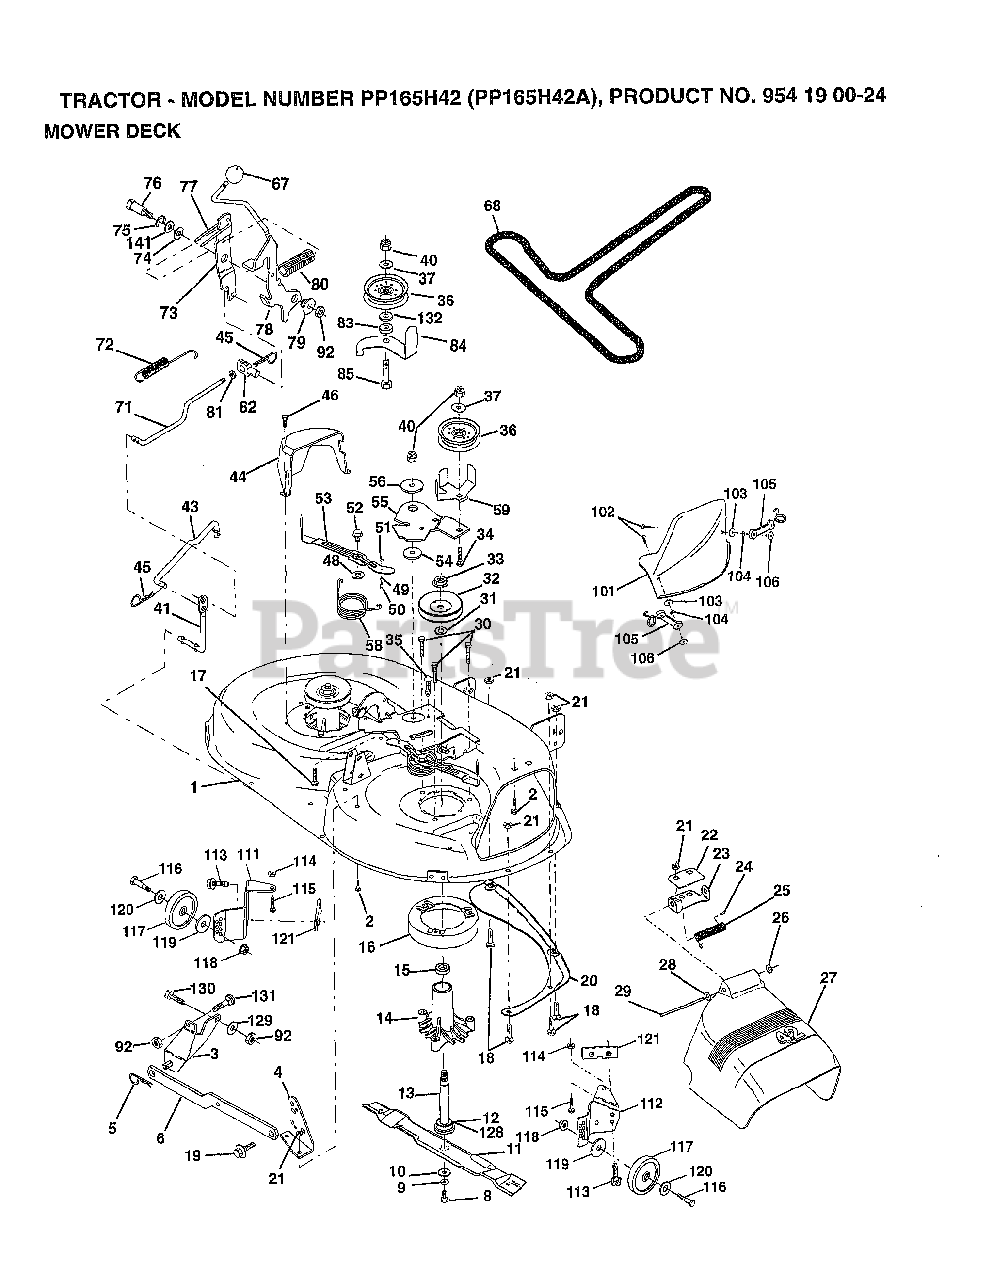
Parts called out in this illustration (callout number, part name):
1	DECK.WELD.42.
2	BOLT
3	BRKT ASM SWAY BAR
4	BRKT DECK SW BAR
8	BLADE BOLT
10	WASHER.HARD.BLADE
11	"BLADE.42"" MULCHER"
12	BEARING.BALL
14	HSG ASM MANDREL
15	BEARING
16	STRIPPER RND MWR
17	BOLT RDHD 3/8-16
18	BOLT
19	BOLT SHD 5/16-18
20	BAFFLE VORTEX 42
22	STIFFENER BRKT
23	DEFLECTOR BRKT
25	SPRING TORSION
27	DEFLECTOR.SHIELD
28	WASHER
29	HINGE ROD
30	"SCREW-THD ROLL,WA"
31	WASHER
32	PULLEY.MANDREL.42
34	BOLT
35	XMAS TREE FASTNER
36	FLAT IDLER PULLEY
37	WASHER
41	PIVOT ROD
43	ROD CLUTCH W/NIBS
44	GUARD MAND LH BLK
46	SCREW.1/4-20X5/8
48	HARD SMALL WASHER
49	ROLLER ASM-CAM
50	SHOULDER BOLT
51	LOCKNUT
52	BOLT.SHLD.5/16-18
53	BRAKE PAD ARM ASM
54	HARDENED WASHER
55	ARM-IDLER
56	SPACER RETAINER
58	SPRING TORSN BRAK
59	GUARD IDLER TUV
67	KNOB.RD.7/16-14
68	BELT.V.T-PATH
71	ROD CLUTCH 38/42
72	RETURN SPRING
73	CLUTCH ARM SECOND
74	WASHER
75	RING
76	SHOULDER BOLT
77	SPRING KEEPER
78	LEVER.ASM.CLUTCH
79	BUSHING
80	SPRING.CLUTCH.MWR
81	TRUNION ADJ
82	NUT
83	WASHER
84	"KEEPER-BELT,FIXED"
85	BOLT RDHD 3/8-16
92	NUT
101	"COVER.MULCH.42"""
102	SCREW
103	WASHER #10
104	LOCKWASHER
105	LATCH ASSY.BAGGER
106	WELDNUT
111	BRACKET.GWHL.LH.
112	BRACKET.GWHL.RH.
113	SCREW
116	BOLT M
117	WHEEL.GAGE.BLK.PL
118	LOCKNUT
119	WASHER
120	WASHER
121	BRACKET.EXTRD.GWL
128	WASHER.FELT.
129	WASHER
130	BOLT
132	WASHER GT
141	WASHER .T
